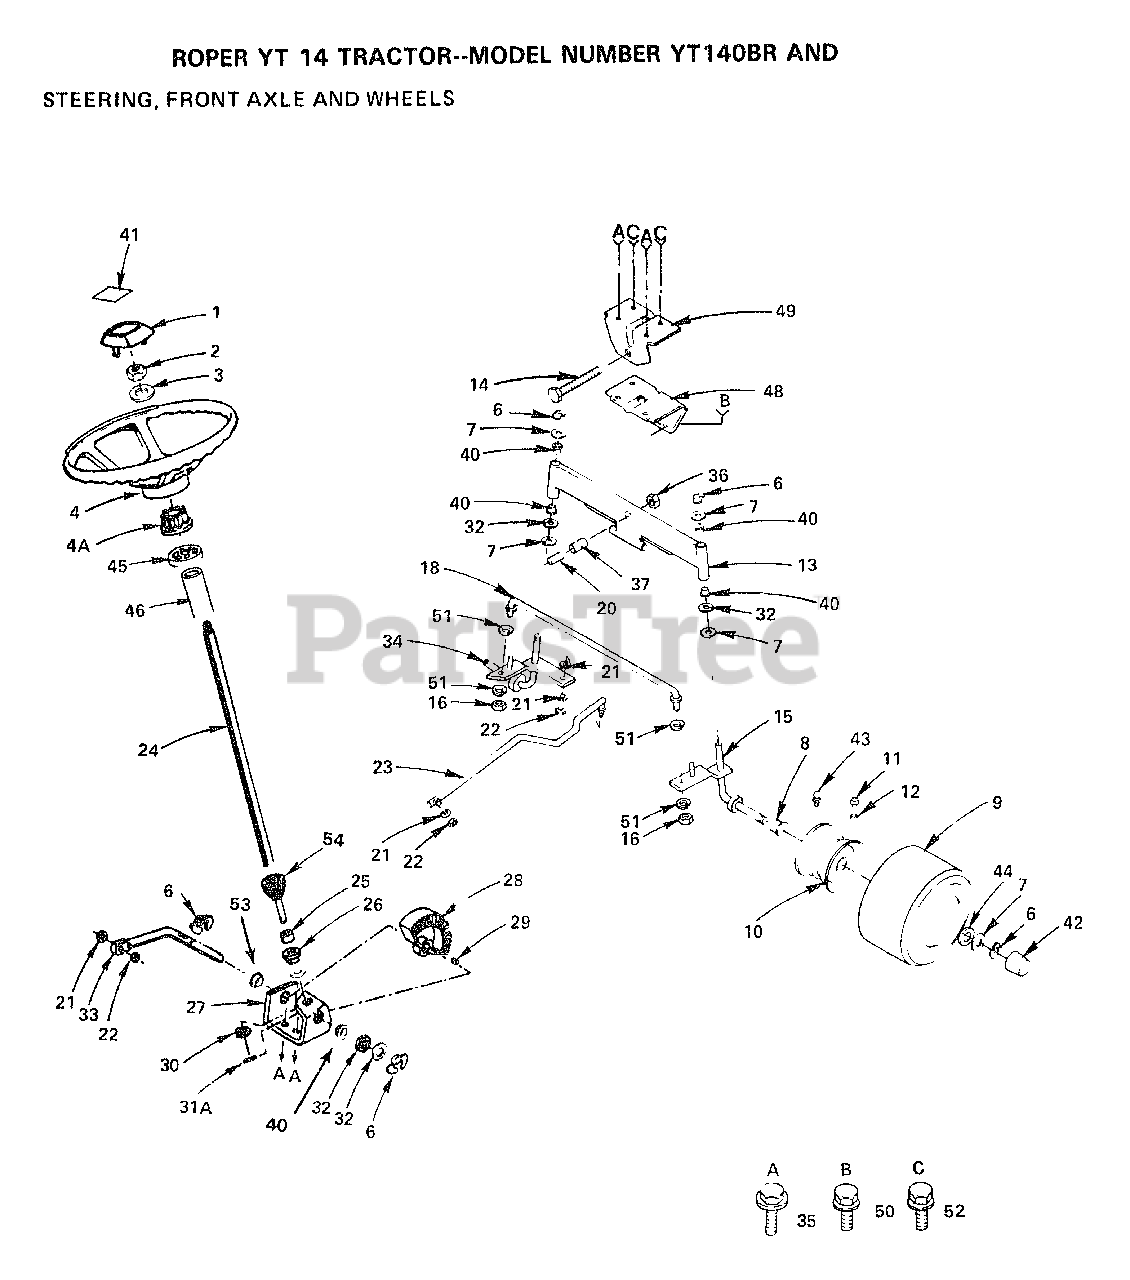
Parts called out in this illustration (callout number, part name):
1	INSERT-WHEEL LT
2	NUT
3	WASHER
4A	ADAPTER LT
6	RING
8	"FLANGE, BEARING"
11	VALVE STEM LT
12	VALVE CAP
13	FRONT AXLE
14	BOLT LT
16	NUT
21	LOCKWASHER
23	LINK-DRAG LT
24	STEERING SHAFT T
25	SHAFT SPACER LT
26	BUSHING
28	GEAR.SECTOR.HYT
29	KEY-WOODRUFF LT
32	WASHER .T
33	ROD STEERING T
34	SPINDLE LH YT
35	SCREW
36	"NUT-LOC,FLANGE LT"
40	COL. SRTG. BEAR.
41	DECAL - STEERING WHEEL
42	HUB CAP
43	FITTING LT
48	SUPPORT.SADDLE.FT
49	SUPPORT-SADDL T
51	LOCKWASHER
52	SCREW GTV
53	NYLINER T
54	GEAR PINION T
